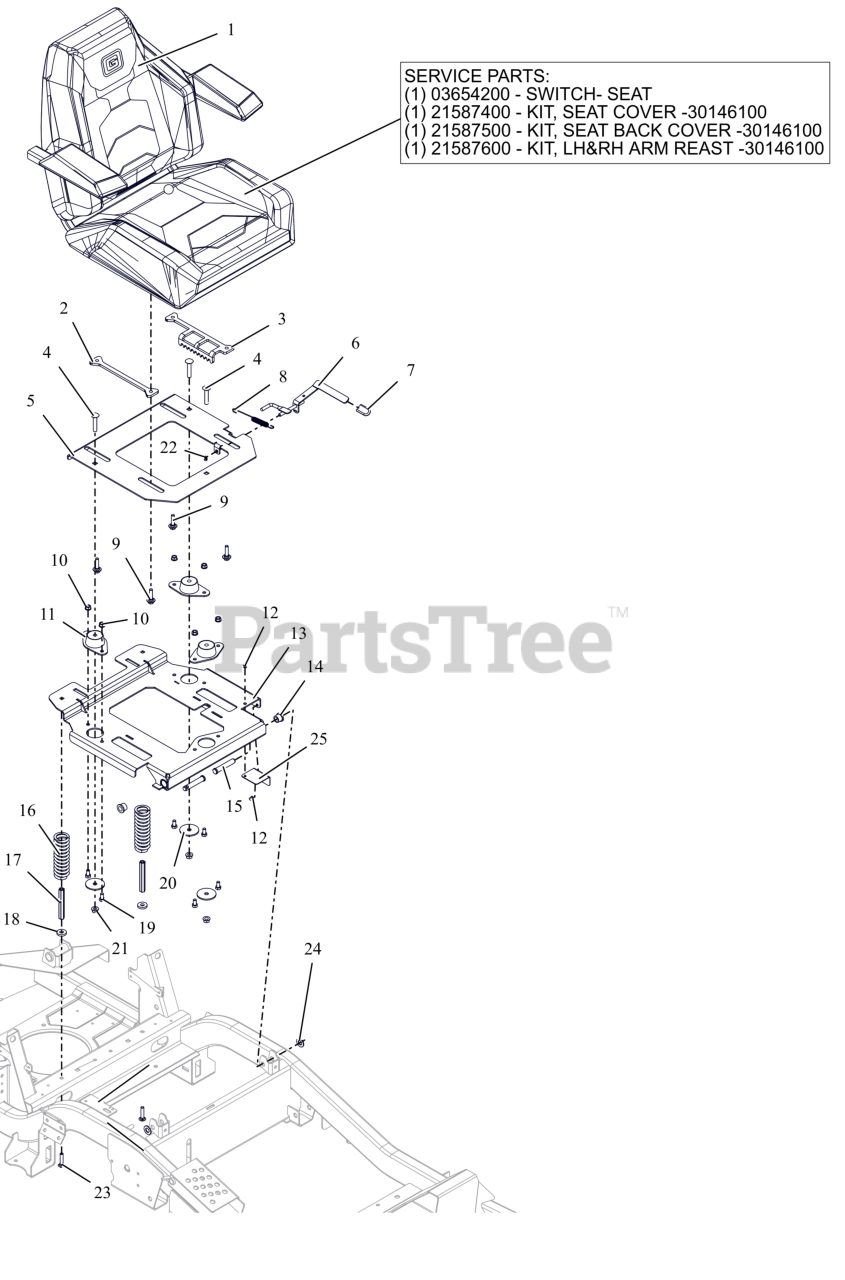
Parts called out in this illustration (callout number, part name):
1	SEAT- HD STEALTH
1	SWITCH- SEAT
1	KIT, SEAT COVER BOTTOM
1	KIT- SEAT BACK COVER
1	KIT- LH&RH ARM REST -09694900
2	PLATE, ADJ SEAT SLIDE (BLACK)
3	PLATE, SEAT ADJ (BLACK)
4	BLT,RHSSN.375-16X2.00 G5 ZCC
5	PLATE- SEAT MOUNTING
6	WLDMT, SEAT SLIDE LEVER
7	GRIP, SEAT LEVER, GREY
8	SG-TENS .06X.482X5.35
9	BLT, SHLDR .31-18 X .175
10	NUT,LK-CTR-FLG .31-18 GF ZCC
11	MOUNT- FAIL-SAFE COMPRESSION
12	RIVET, .1875 AL/AL .126-.250
13	WLDMT- ISO MTG PLATE
14	BSHG, FLG .516X.750X.625X.937
15	PIN, SLIC-.500X42.70X2.31 -ZC
16	SPRING, COMPRESSION SEAT 224LB
17	NUT, COUPLING 5/16X18 X 3.75
18	WSHR, FLT .406X1.00X.188 ZCC
19	BLT, HEX .31-18X.625 G5 ZCC
20	WSHR-FL-STL 0.406X2X0.125 ZCC
21	NUT-LK-CTR-FLG .375-16 GF ZCC
22	NUT-PUSH .312
23	BLT,RHSN .31-18X1.50 G5 ZCC
24	WSHR-FL-NYL .518X1.000X.080
25	GUARD, SEAT FAN (SH)(BLACK)
